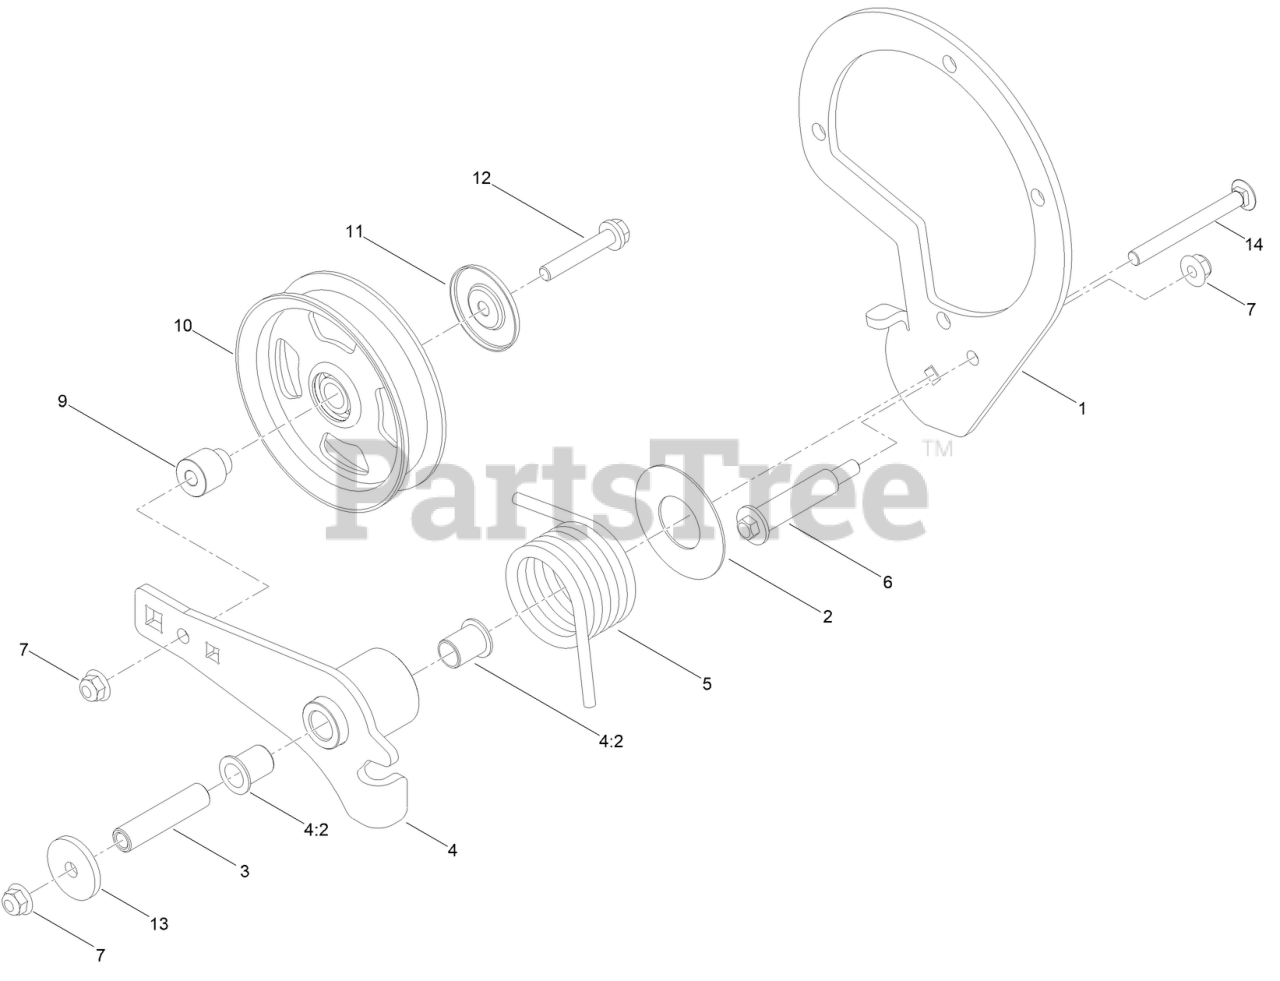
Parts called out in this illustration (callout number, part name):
1	PLATE-MOUNT, TENSIONER
4	IDLER ARM ASM
4:2	BUSHING-FLANGE
5	SPRING-TORSION
6	BOLT-SHOULDER
7	NUT-HF, NI
9	BUSHING-IDLER
10	PULLEY-IDLER, FLAT
11	SHIELD-DUST
12	SCREW-HHF
13	WASHER
14	SCREW-CARR
